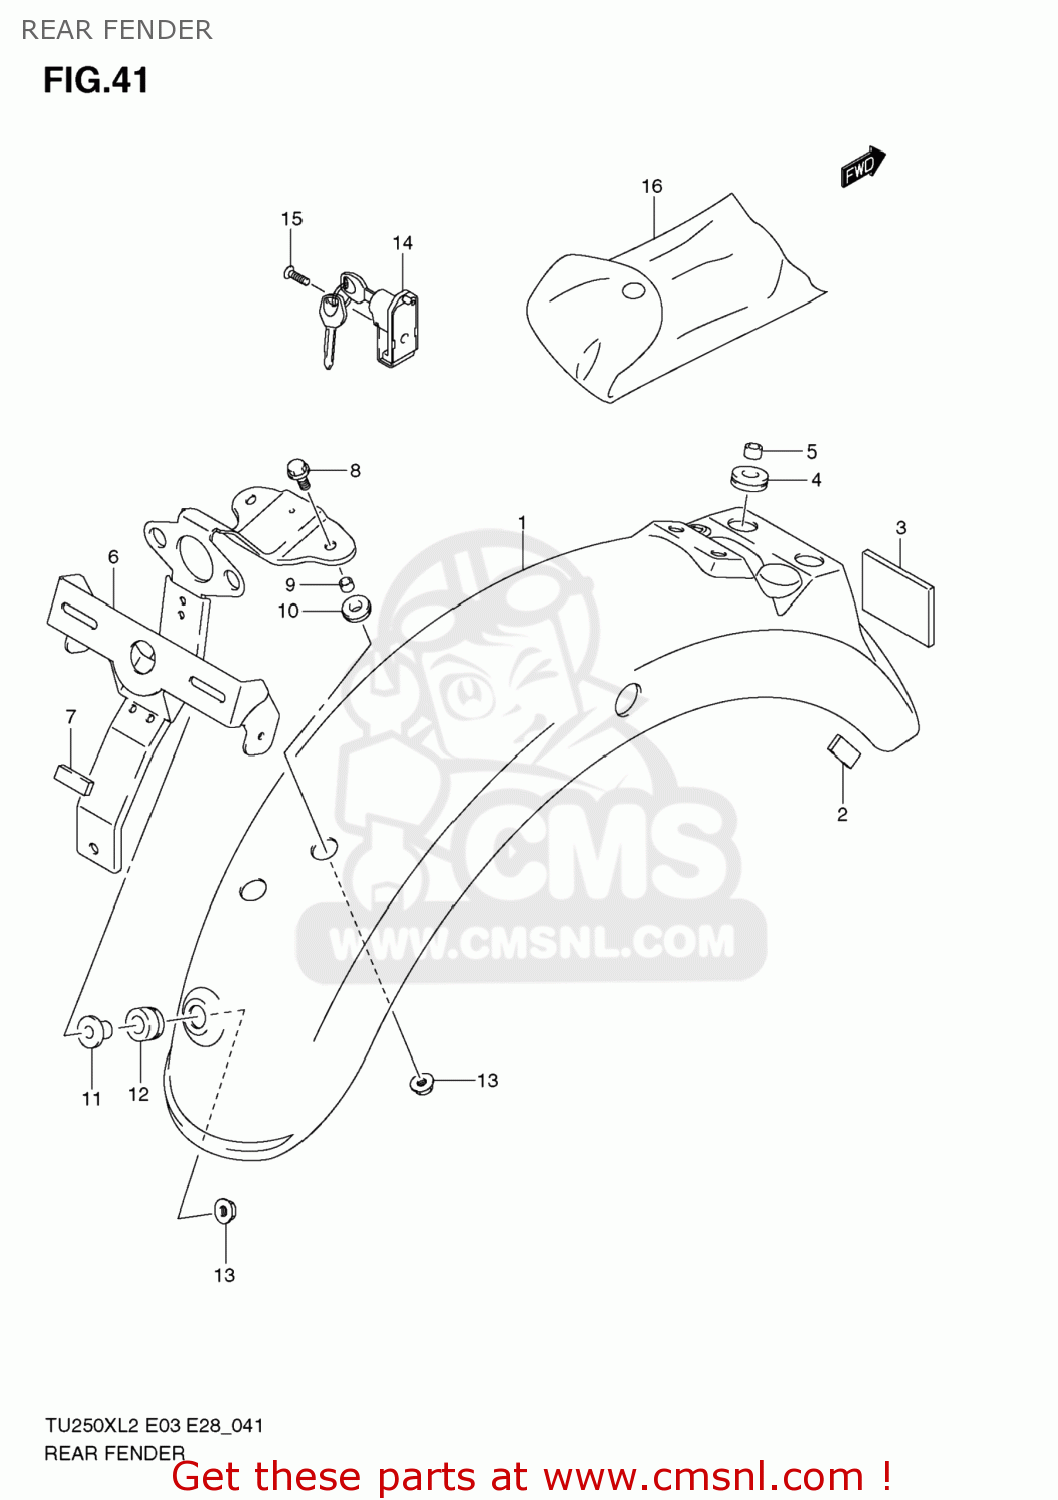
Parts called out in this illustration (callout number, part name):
1	FENDER,RR
2	CUSHION,RR FENDER
3	CUSHION,RR FENDER
4	CUSHION
5	SPACER,8.5X14X9
6	BRACE,RR COMB & LIC
7	CUSHION,LIC
8	BOLT
9	SPACER(6.5X10.5X15)
10	CUSHION
11	SPACER(6.5X10X11.6)
12	CUSHION
13	NUT
14	LOCK SET,HELMET
15	SCREW
16	TOOL SET
